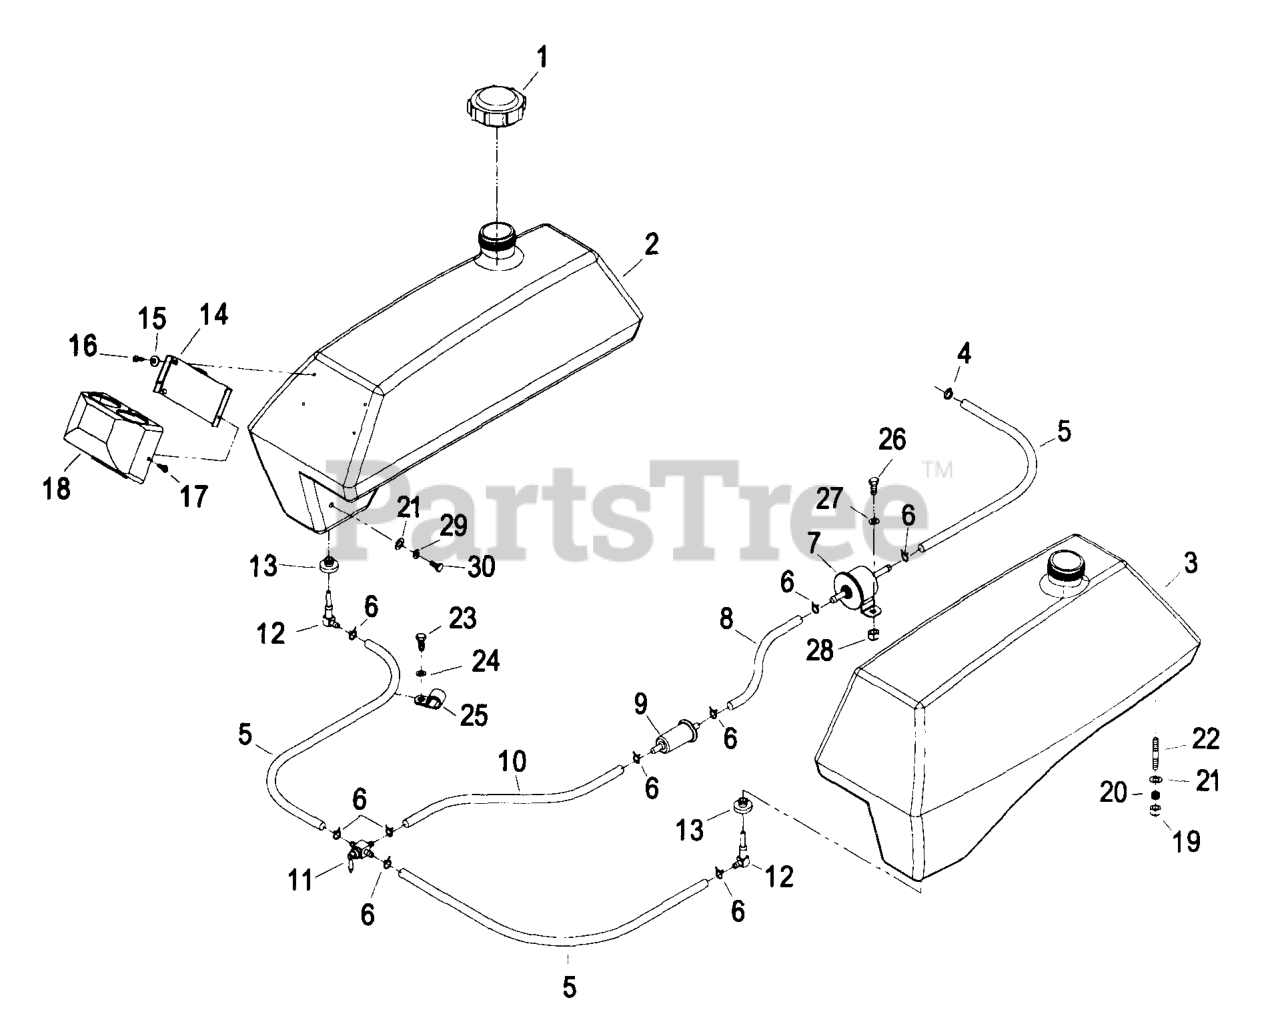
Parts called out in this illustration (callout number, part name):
1	CAP-FUEL
4	CLAMP-HOSE
5	HOSE-FUEL
7	Fuel Pump
8	HOSE-FUEL
9	Fuel Filter
10	HOSE-FUEL
11	VALVE-FUEL
12	ELBOW-TANK, FUEL
14	BRACKET,GAUGE MOUNT
15	WASHER-SPRING
18	COVER,GAUGES
20	SPRING-TANK, FUEL
22	STUD
24	WASHER-LOCK
25	CLIP-LOOM
29	WASHER-LOCK
